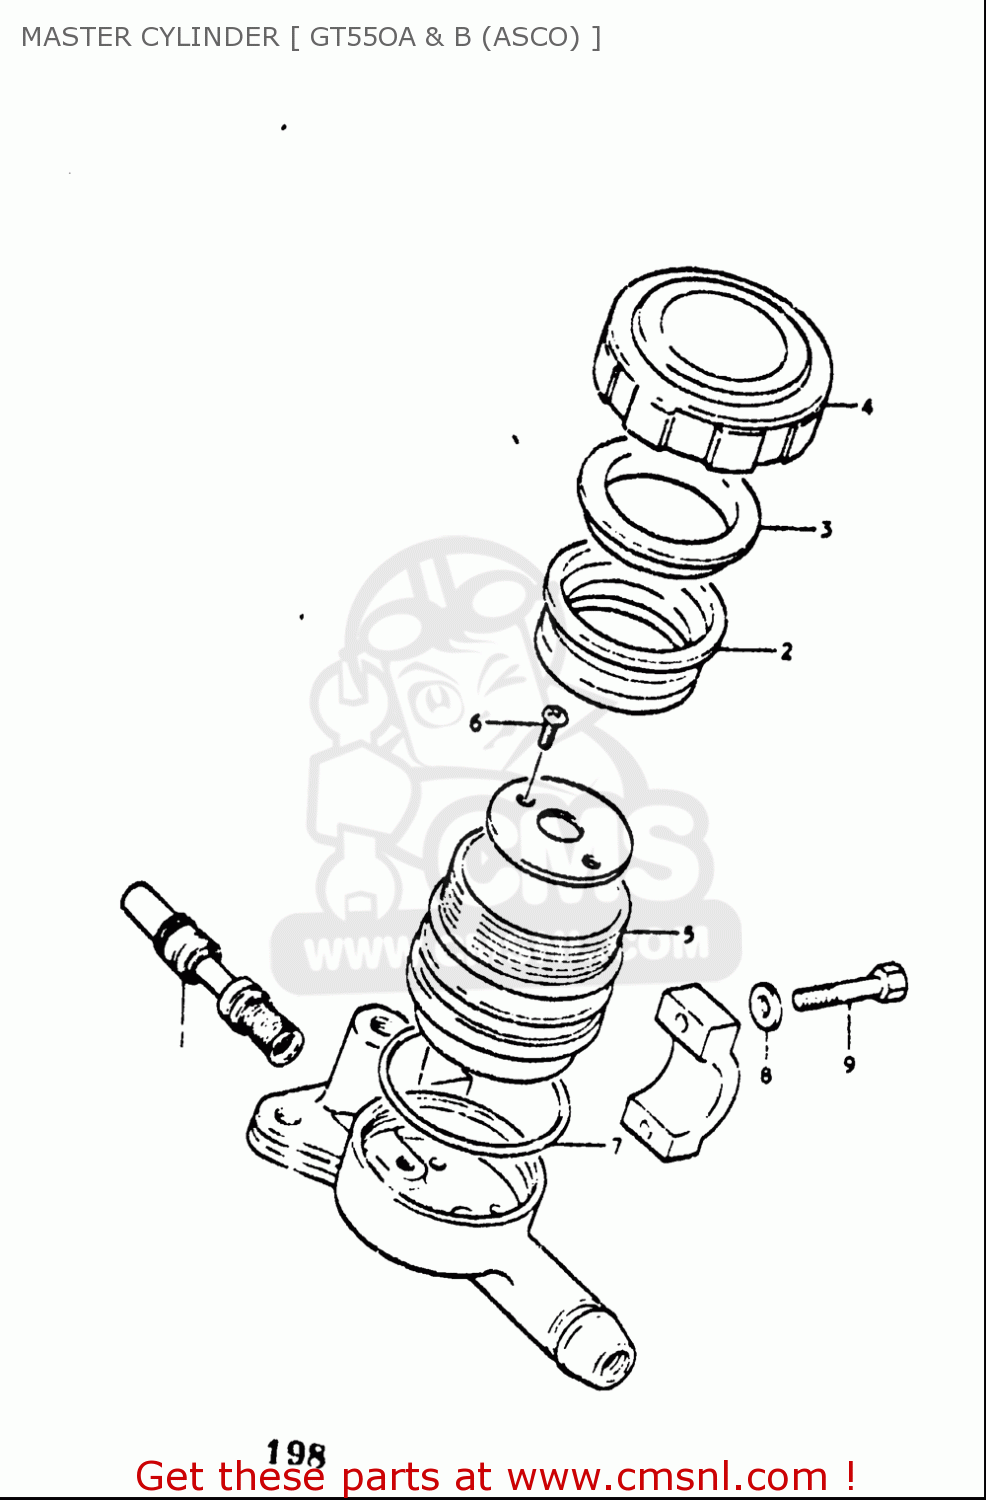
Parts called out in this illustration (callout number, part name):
1	PISTON & CUP SET
2	DIAPHRAGM
3	PLATE
5	RESERVOIR
7	O RING
8	WASHER
9	BOLT
